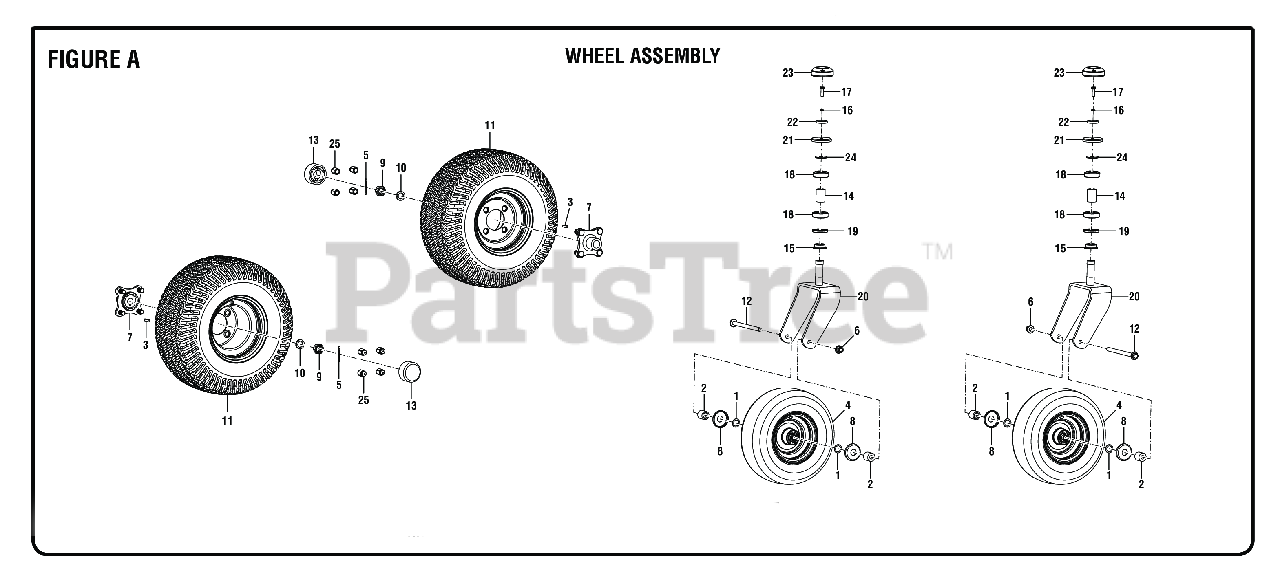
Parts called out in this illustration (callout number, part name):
1	Washer (OD28 x ID20.5 x 2t)
2	Caster Wheel Spacer
3	Key (6 mm x 6 mm x 30 mm)
4	Caster Wheel
5	Drive Shaft Cotter Pin
6	Flange Nut (M12)
7	Wheel Hub
8	Front Wheel Bearing Cover
9	Castle Nut (M20)
10	Lock Spring Washer (20.6 x 30.6 x 4.8t)
11	Rear Wheel Assembly
12	Flange Bolt (M12 x 170 mm, Hex Hd.)
13	Wheel Hub Cover
14	Bearing Assembly Spacer
15	Bearing Assembly Base
16	Lock Washer (OD9.8 x ID8.5 x 5t)
17	Bolt (M8 x 25 mm)
18	Roller Bearing (ID 25 mm x OD 52 mm)
19	Rubber Seal
20	Caster Fork
21	Bearing Assembly Cap
22	Fender Washer (OD37 x ID8.4 x 6t)
23	Caster Fork Cover
24	Fender Washer (OD40 x ID12.5 x 2t)
25	Acorn Nut (M14)
